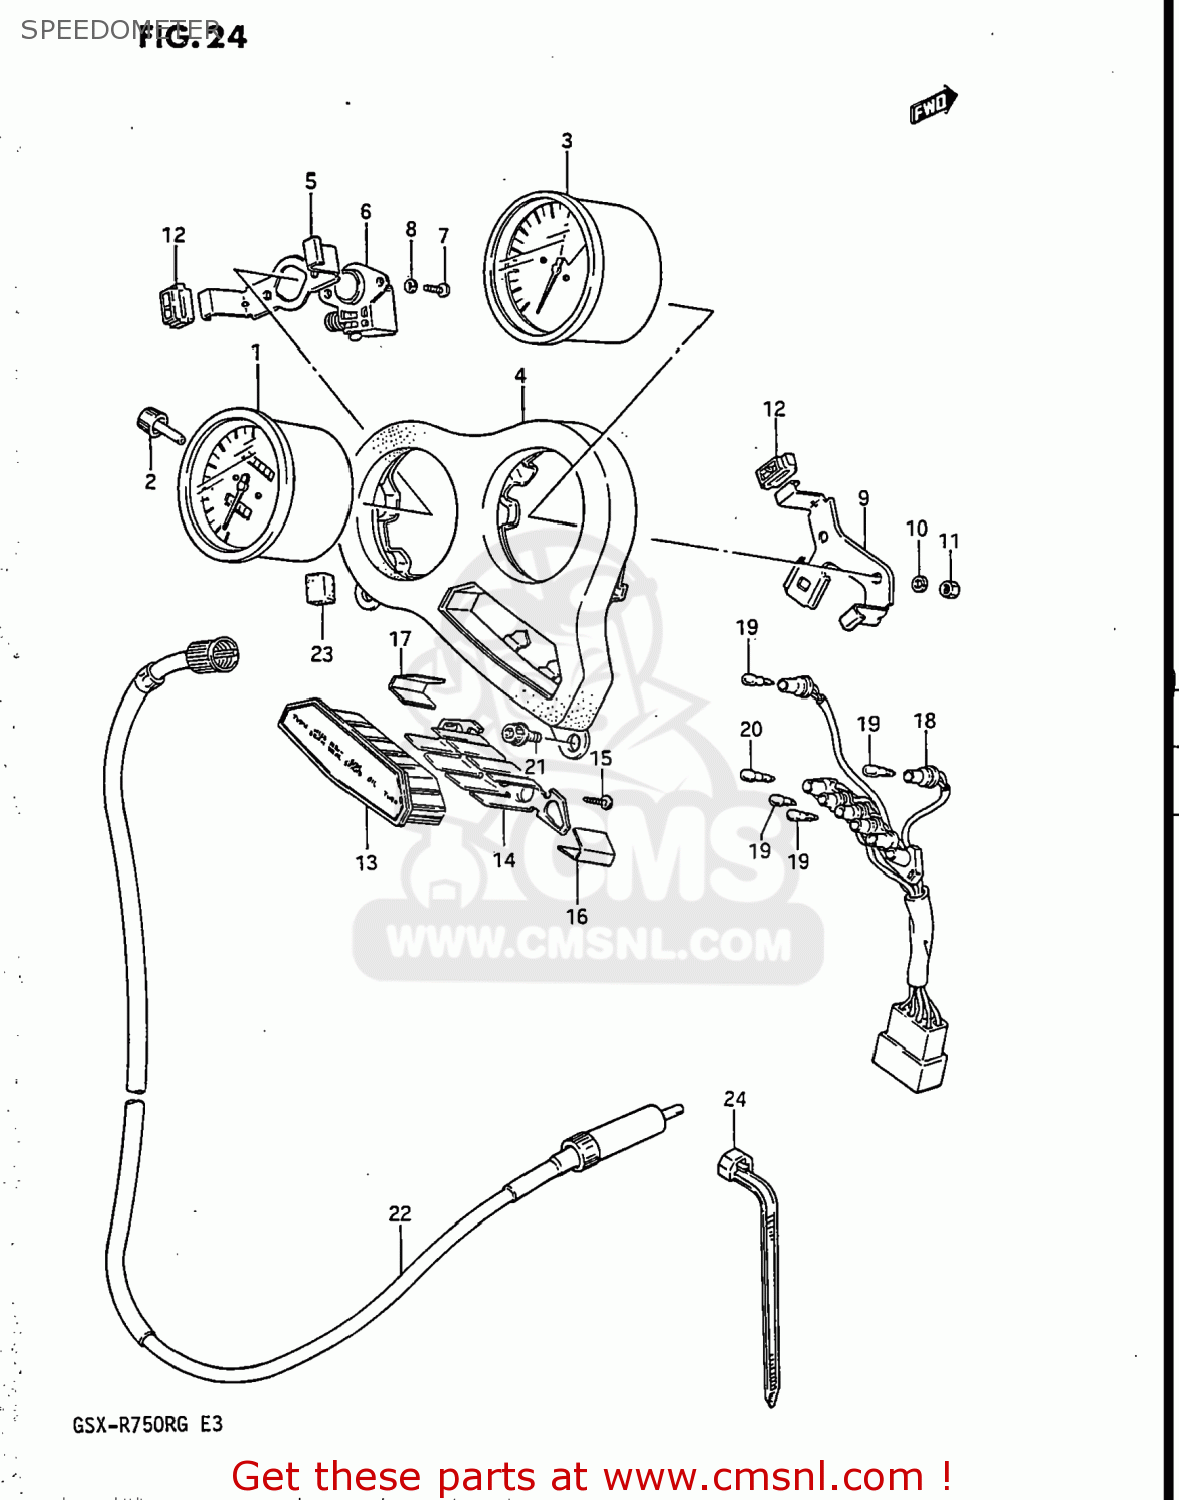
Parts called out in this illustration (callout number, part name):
1	SPEEDOMETER (MILE/KILO)
2	KNOB,TRIP
3	TACHOMETER
4	BRACKET, METER
5	PLATE,SPEEDOMETER
6	BOX,METER GEAR
7	SCREW
8	LOCK WASHER
9	PLATE,TACHOMETER
10	WASHER
11	NUT
12	CUSHION
13	CASE,PILOT LAMP
14	PLATE,PILOT LAMP
15	SCREW
16	PLATE,TURN,R
17	PLATE,TURN,L
18	SOCKET
19	BULB(12V3W,WB371,T7)
20	BULB(12V1.7W,WB372,T7)
21	BOLT
22	CABLE ASSEMBLY,SPEEDOMETER
23	CUSHION,METER
24	CLAMP(L:95)
